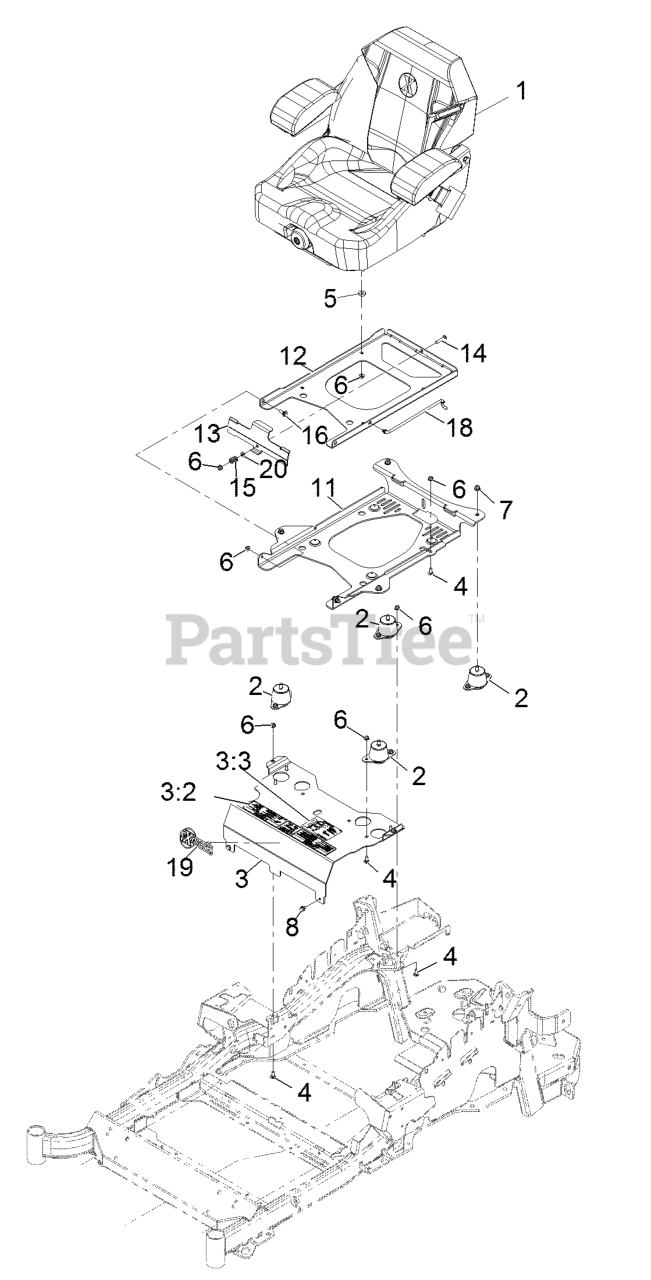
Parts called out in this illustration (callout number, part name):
1	KIT-SUSPENSION SEAT
2	ISOLATOR-SEAT
3	MOUNT-SEAT
3:2	DECAL-CONSOLE
3:3	DECAL-SERVICE AID
4	SCREW-CARR
6	NUT-HF, NI
7	NUT-HF, NI
11	PLATE-TILT, SEAT SUPPORT
12	PLATE-FRAME, SEAT
13	PLATE-LATCH, SEAT
14	BOLT-CARR
15	SPRING-COMPRESSION
16	SCREW-SHOULDER
18	ROD-PROP
20	WASHER-PLAIN
